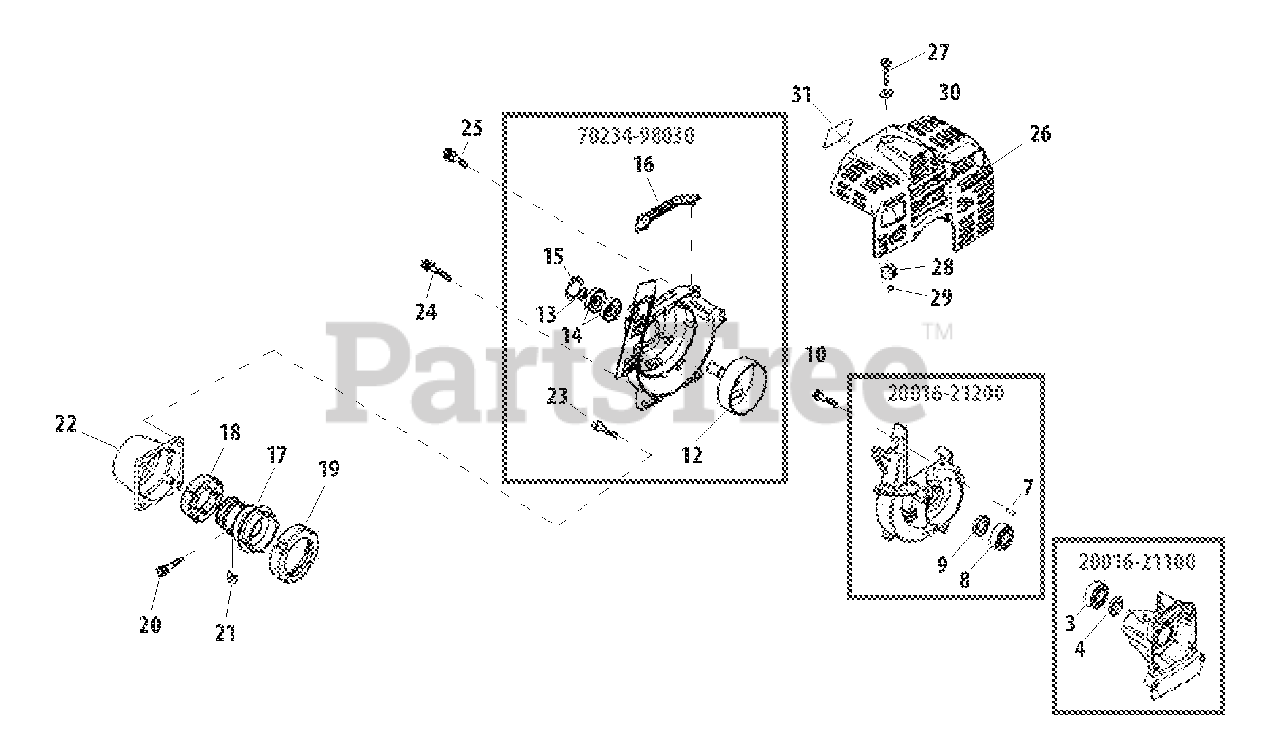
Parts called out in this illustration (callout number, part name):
3	BEARING, BALL 6001 C3
4	SEAL, OIL 12
7	PIN, LOCATING Ø4×8
8	BEARING, BALL 6001 C3
9	SEAL, OIL 12
10	BOLT 5×25
12	DRUM, CLUTCH
13	RING, SNAP WR10
14	BEARING, BALL 6000ZZ
15	RING, SNAP Ø26
16	CUSHION
17	JOINT
18	CUSHION, FRONT
19	HOLDER, REAR CUSHION
20	BOLT M5×25
21	D-WASHER
22	COVER, AV CUSHION (RED)
23	BOLT M5×16
24	BOLT M5×35
25	BOLT M5×16
26	COVER, ENGINE
27	BOLT 5×25
28	INSULATOR 5 MM
29	CLIP
30	WASHER 5 MM
31	LABEL - MODEL
20016-21100	CRANKCASE ASSY, S
20016-21200	CRANKCASE ASSY, M
70234-98030	FAN CASE ASSY
